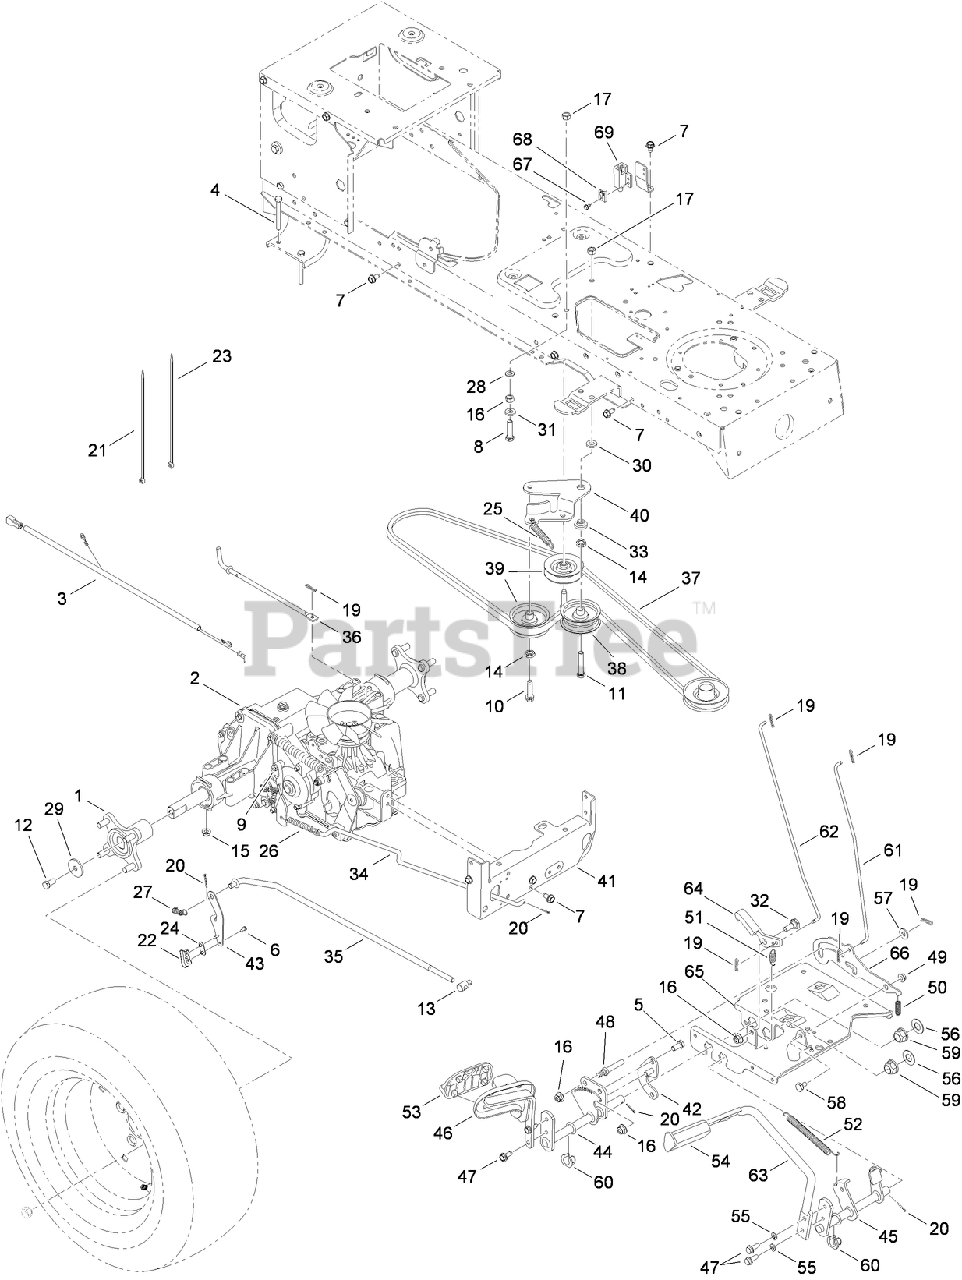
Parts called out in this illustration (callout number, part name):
1	WHEEL HUB ASM
2	TRANSMISSION ASM
3	HARNESS ASM
4	SCREW-HEX
5	SCREW-HH
6	SCREW-HWHTF
7	SCREW-TAP
8	SCREW-HH
9	SCREW-HWHTF
10	SCREW-TAP
11	SCREW-HH
12	SCREW-HH
13	FERRULE
14	NUT-JAM
15	NUT-LOCK, FLANGE
16	NUT-LOCK, FLANGE
17	NUT-LOCK, FLANGE
19	PIN-COTTER
20	PIN-COTTER
21	TIE-CABLE
22	SWITCH-SPRING, SHORT
23	TIE-CABLE
24	PLATE-INSULATOR
25	SPRING-EXTENSION
26	SPRING-EXTENSION
27	SPRING-EXTENSION
28	WASHER-LOCK
29	WASHER-FLAT
30	WASHER-FLAT
31	WASHER-FLAT
32	BOLT-SHOULDER
33	SPACER-SHOULDER
34	ROD-BRAKE
35	ROD-CONTROL
36	ROD-DISENGAGE
38	PULLEY-IDLER, FLAT
39	PULLEY-IDLER, Y TYPE
40	BRACKET-IDLER, CENTER DOUBLE
41	BRACKET-TRANSMISSION
42	BRACKET-CONTROL
43	BRACKET-ACTUATOR
44	CONTROL ASM
45	SPEED CONTROL ASM
46	CONTROL PEDAL ASM
47	SCREW-HWH
49	NUT-LOCK, FLANGE
50	SPRING
51	SPRING-EXTENSION
52	SPRING-EXTENSION
53	PAD-PEDAL
54	PAD-BRAKE
55	WASHER-LOCK
56	WASHER-FLAT
57	WASHER-FLAT
58	BOLT-SHOULDER
59	BEARING-FLANGE
60	BEARING-FLANGE, HEX (SPLIT)
61	ROD-BRAKE, LOCK
62	ROD-CONTROL, CRUISE
63	PEDAL-BRAKE
64	LATCH-CRUISE
65	BRACKET-SUPPORT, STEERING
66	BRACKET-LOCKOUT
67	SCREW-TAP
68	PLATE-SWITCH
69	SWITCH-INTERLOCK
